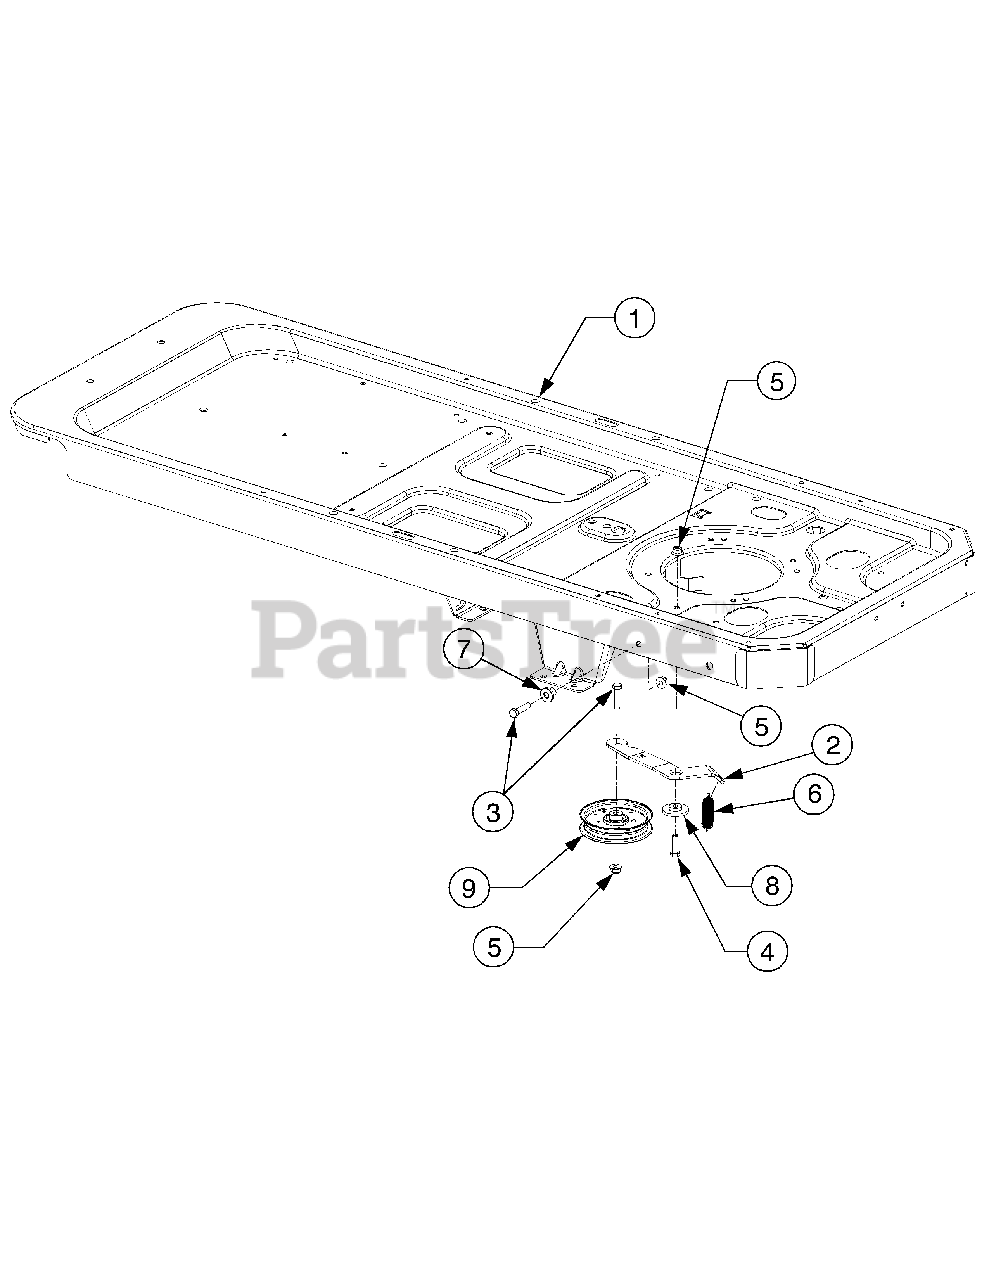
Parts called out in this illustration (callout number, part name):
3	Screw, Hex Cap, 3/8-16 x 1.5 GR5
4	Screw, Hex Cap, 3/8-16 x 1.25 GR5
5	Nut, Hx Insert Flnge Lck, 3/-16 GrF
6	Spring, Extension, .75 x 5.06
7	Spacer, Shoulder, .39 x 1.0 x .7
8	Screw, Shoulder, .884 x .19
9	Pulley, Idler, 4.25 Dia.
